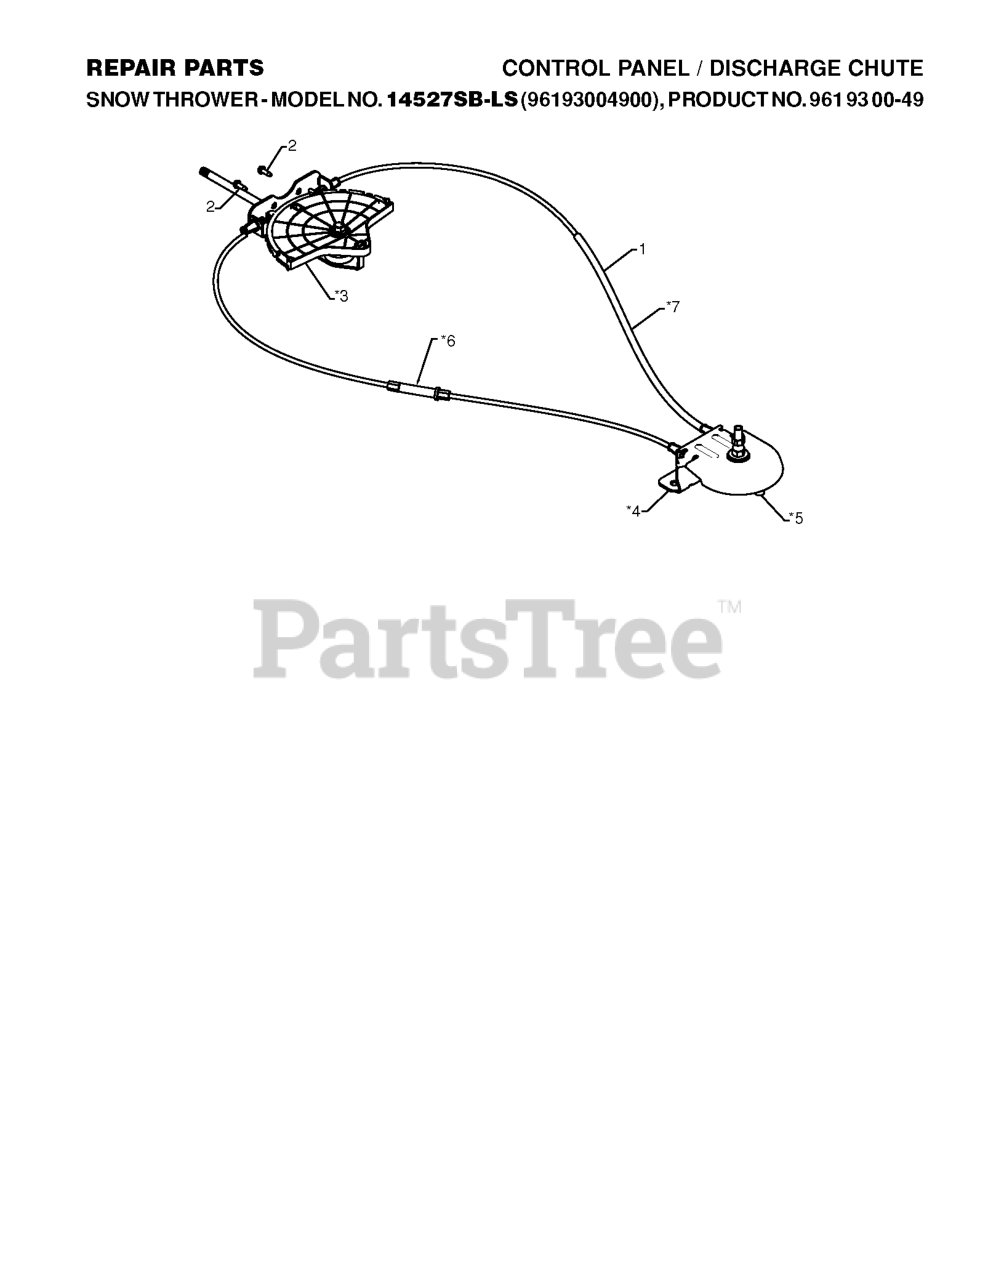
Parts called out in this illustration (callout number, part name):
1	RB LEVER.CABLE.ASM.ROTATR.PLTD
2	SCREW #10-24 X 5/8
3	CHUTE.ROT.HEAD.SERVICE
4	SNOW.PIVOT.BRKT.GRY.SERVICE
5	SNOW.PIVOT.PULLY
6	SNOW.CABLE.ASM.ADJUSTABLE.GRAY
7	SNOW.CABLE.ASM.SERVICE
